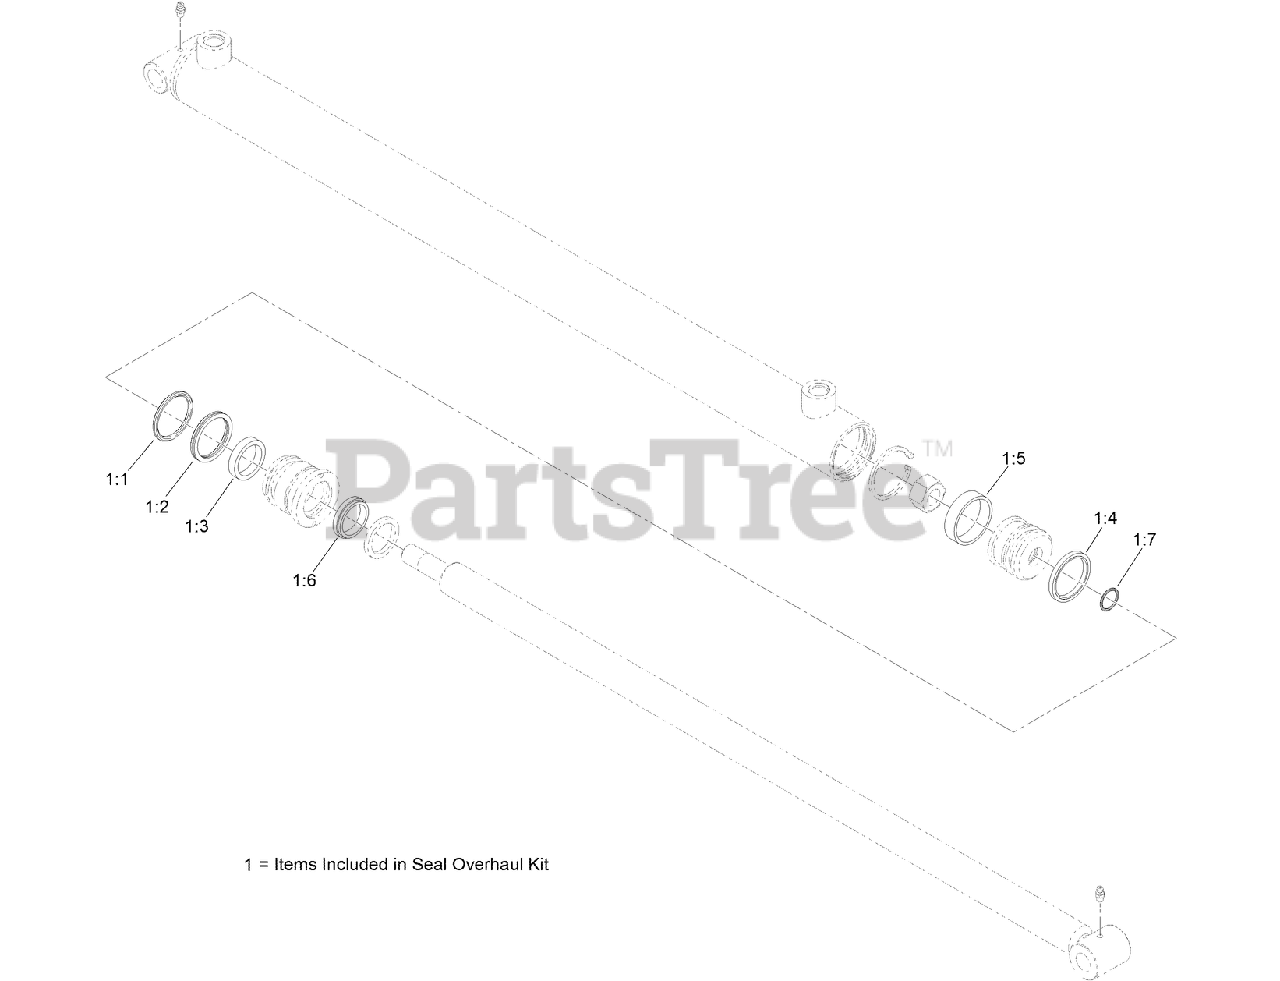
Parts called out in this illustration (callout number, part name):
1	SEAL REPAIR KIT
1:1	Deck ASM
1:2	Deck ASM
1:3	Deck ASM
1:4	Deck ASM
1:5	BT SEAL
1:6	Deck ASM
1:7	Deck ASM
